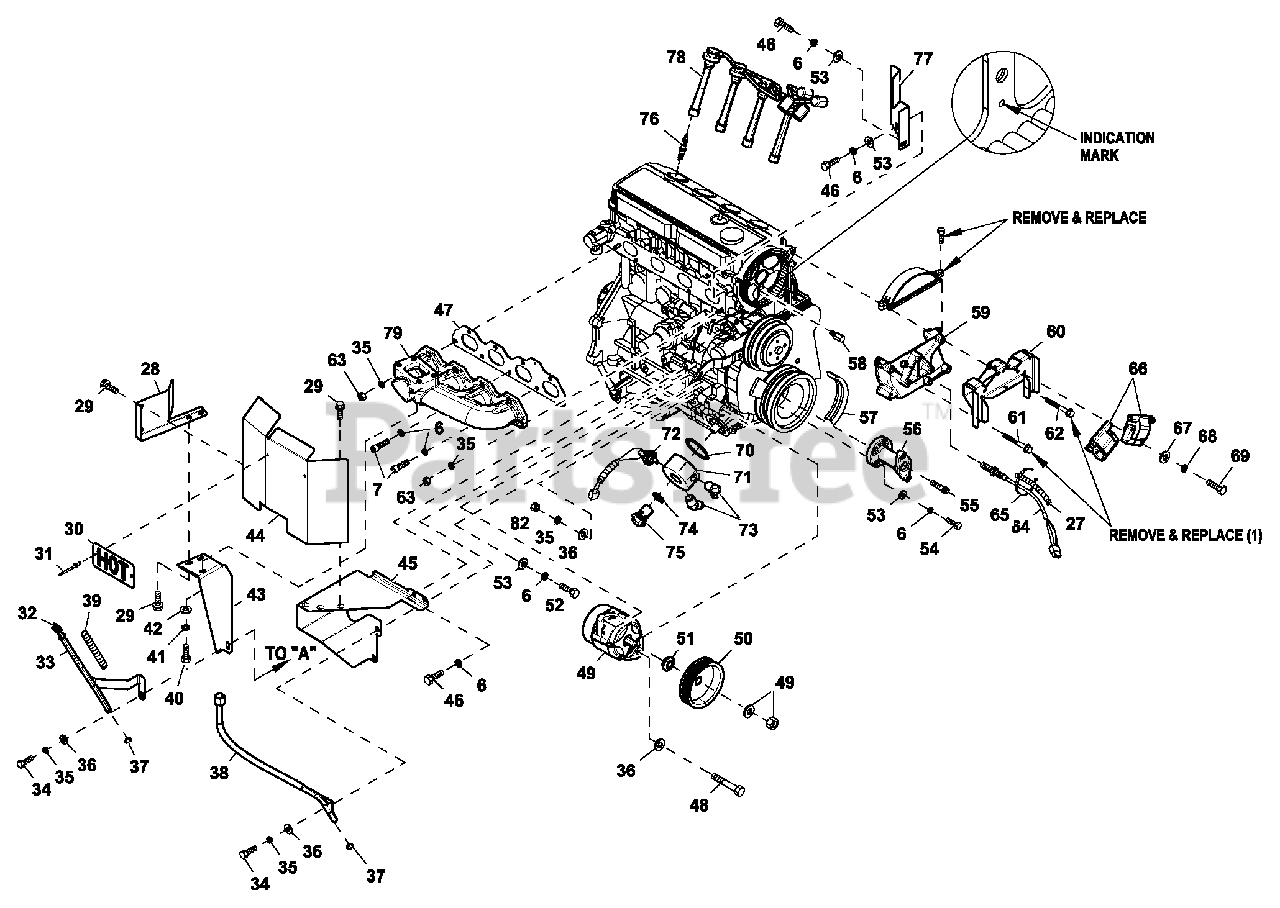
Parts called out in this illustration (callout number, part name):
5	MANIFOLD INTAKE (MACHINED)
6	WASHER LOCK M8-5/16
27	CONDUIT FLEX .25"ID
28	SHIELD INNER HEAT 2.4L TURBO
29	SCREW HHTT M6-1.0 X 12 ZINC
30	PLATE "HOT"
31	RIVET POP .1 2 5X 0 .3 3 7 STEEL
32	ASSEMBLY DIPSTICK G2.4L
33	ASSY DIPSTICK TUBE 2.4 G2
34	SCREW HHC M10-1.25X 20 C8.8
35	WASHER LOCK M10
36	WASHER FLAT 3/8-M10 ZINC
37	O-RING SIZE 9.0MM X 2.0MM NITR
38	TUBE TURBO OIL RETURN G2 2.4L
39	CONDUIT THERMAL FLEX 13MM ID
40	SCREW HHC M6-1.0 X 16 C8.8
41	WASHER LOCK M6-1/4
42	WASHER FLAT 1/4-M6 ZINC
44	HEAT SHIELD TURBO 2.4L
45	BRACKET HEAT SHIELD 2.4L
46	SCREW HHC M8-1.25X 16 C8.8
47	GASKET EXHAUST MANIFOLD
48	SCREW HHC M10-1.5X 120 C8.8
49	ALTERNATOR DC W /OUT PULLEY
50	PULLEY DC ALTERNATOR
51	SPACER DC ALTERNATOR PULLEY
52	SCREW HHC M8-1.25X 25 G10.9
53	WASHER FLAT 5/16-M8 ZINC
54	SCREW HHC M 8 -1 .25X 35 G8.8
55	SCREW SHC M14-1.5X 35 G10.9
56	ADAPTER 2.4L CRANKSHAFT MACH
57	POLY V-BELT G2
58	CAM SENSOR PIN ASSY
59	COVER CAM GEAR G2 REWORKED
60	BRACKET ASM-2.4L COIL G2
63	NUT HEX M10-1.25 G 8Y E LC H R
64	VR SENSOR ASSY 3/8-24 LOW SENS
65	TIE WRAP UL 7.4"X .19" BLK
66	COIL-2.4LG2 IGNITION
67	WASHER FLAT #10 ZINC
68	WASHER LOCK #10
69	SCREW HHM # 10 -3 2X 1 -1 /4
70	O-RING 2.5"X 2.75"X 1/8" VITON
71	ADAPTOR OIL FILTER 2.4L G2
72	HARN LOW OIL PRESS SWITCH ASSY
73	ADAPTOR 45D JIC37 1/2NPT X (
74	O-RING 1 "X 1.25" X 1/8" VITON
75	NUT OIL FILTER ADAPTOR 2.4L G2
76	PLUG SPARK
77	SHIELD HEAT IGNITION COIL 2.4L
78	SPARK PLUG WIRE SET 2.4L G2 IG
79	MANIFOLD EXH 60K G2 TURBO (MA)
82	NUT HEX M10-1.5 G 8YE L CHR
